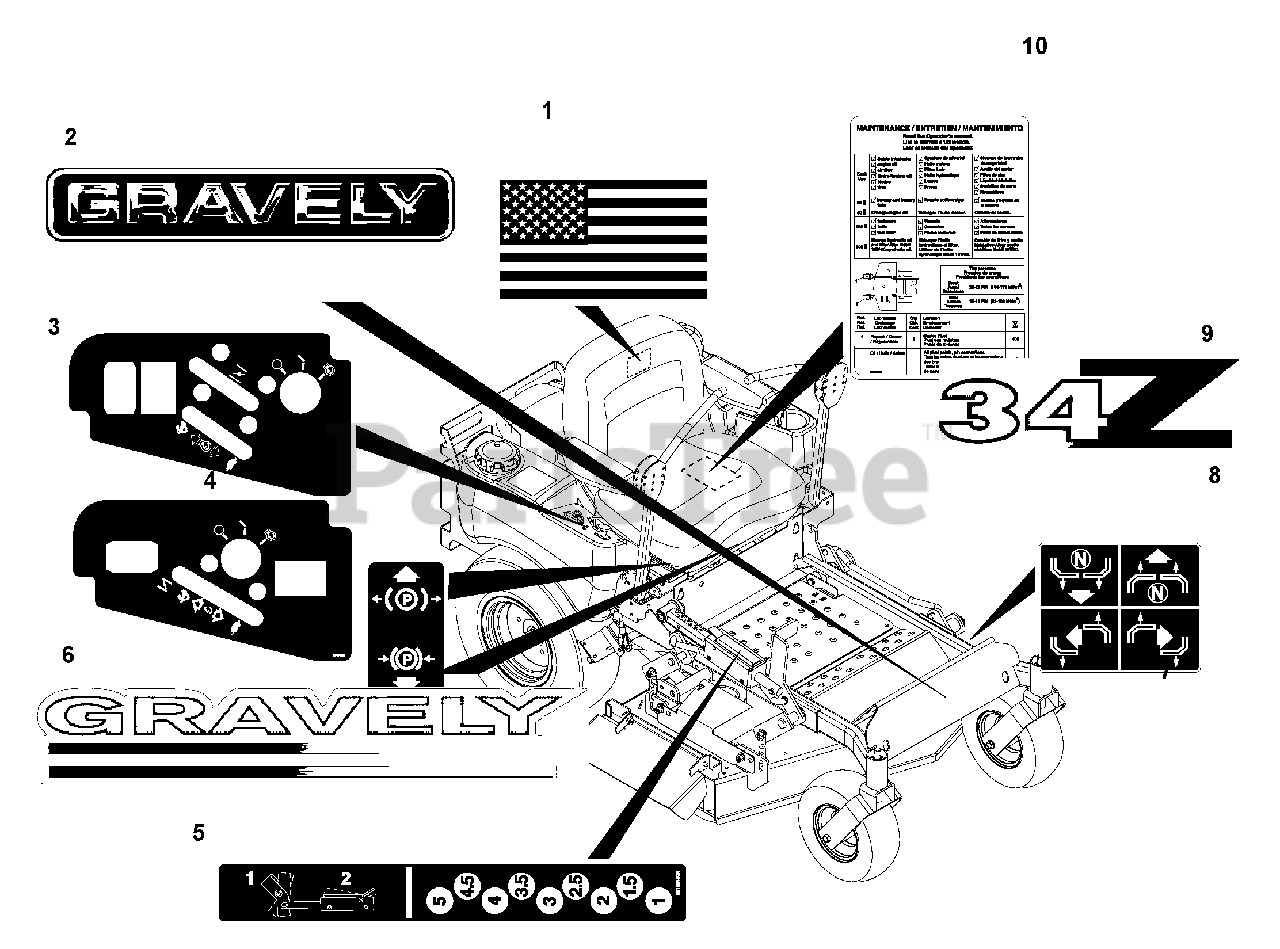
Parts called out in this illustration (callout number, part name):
1	Decal, American Flag
2	Decal, 15" Gravely Logo
3	Decal, Control Panel
4	Decal, Parking Brake Lever
5	Decal, Height of Cut
6	Decal, ZT Hood
7	Decal, Belt Diagram (056, 314)
7	Decal, Belt Diagram (065)
8	Decal, Instructional Steering
9	Decal, PM 34Z (056, 314)
9	Decal, PM 44Z (065)
10	Decal, Service Instructions
